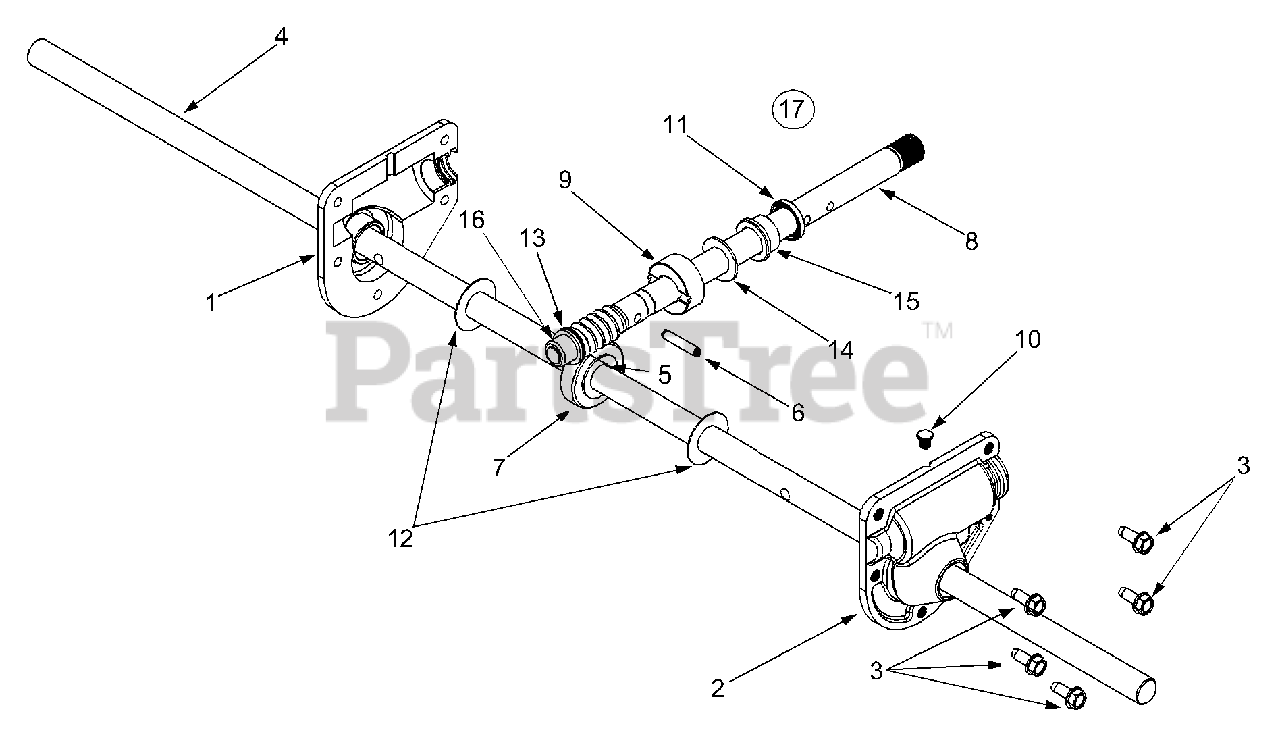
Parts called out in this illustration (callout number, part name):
1	Housing-R.H.
2	Housing-L.H.
3	Hex Screw 1/4-20 x .75
4	Spiral Axle 22"
4	Spiral Axle 24"
5	Key
6	Pin-Spiral
7	Gear-Worm
8	Shaft-Worm
9	Collar-Thrust
11	Seal-Oil
12	Washer-Flat
13	Washer-Flat
14	Washer-Flat
15	Bearing-Flange
16	Bearing-Flange
17	Ass'y. Complete 22"
